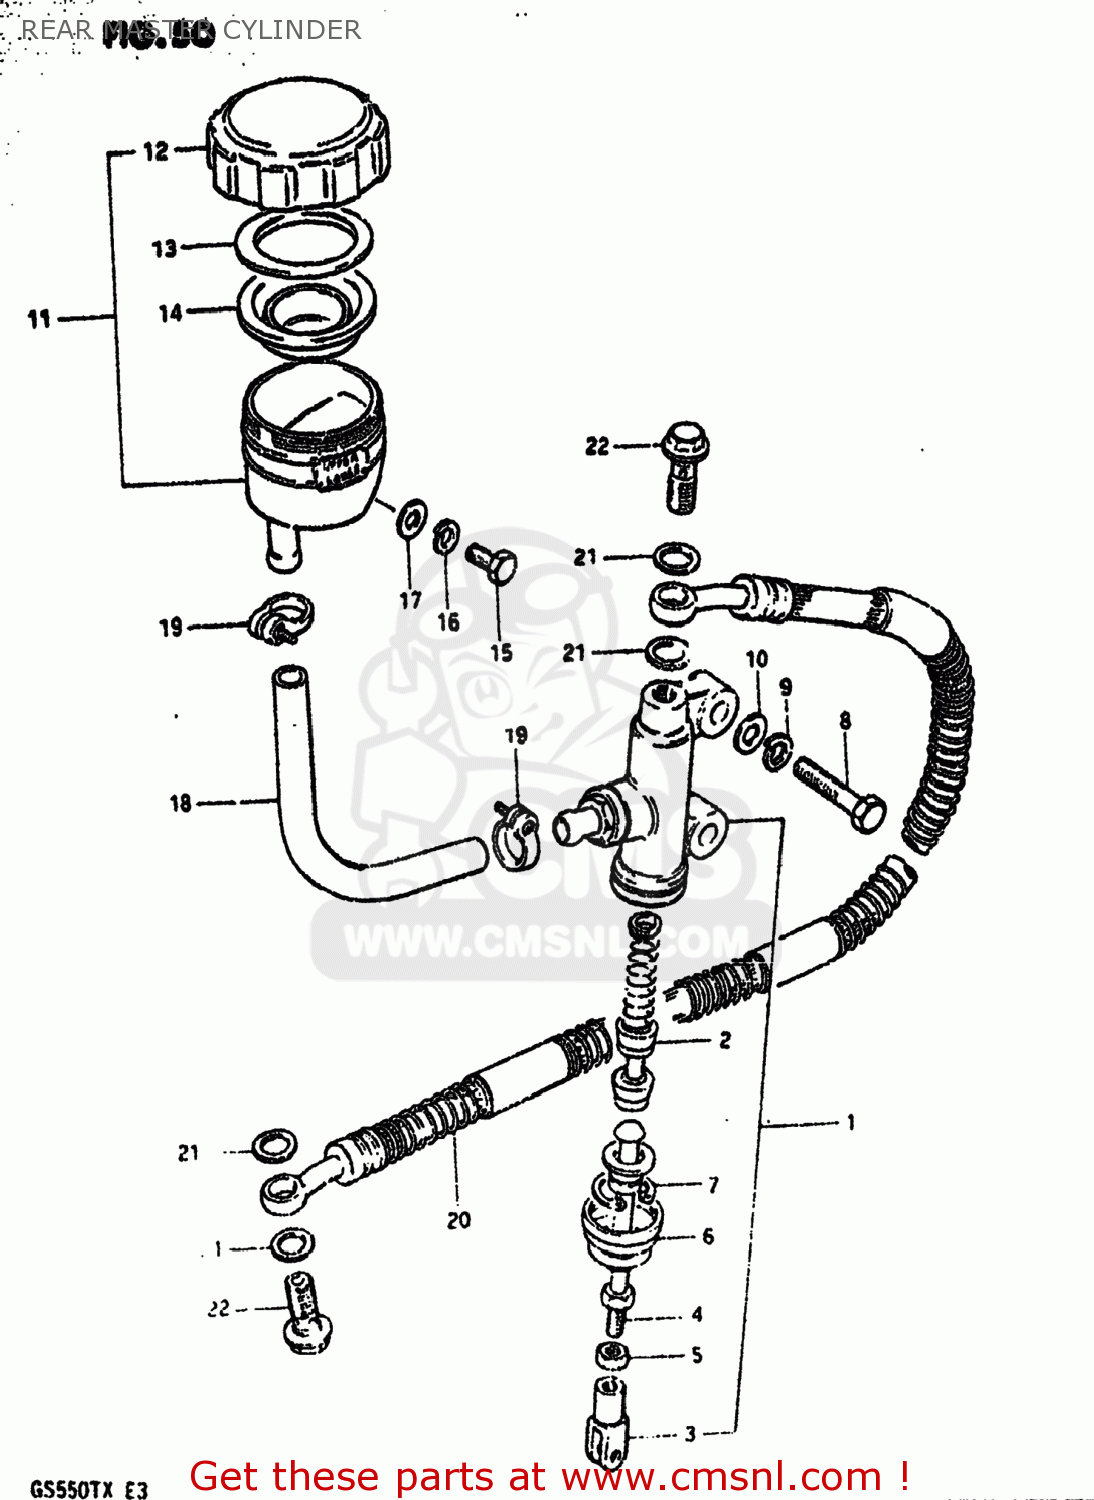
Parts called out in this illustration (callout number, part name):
1	CYLINDER ASSEMBLY,REAR MASTER
2	PISTON/CUP SET
3	YOKE
4	ROD,PUSH
5	NUT
6	BOOT
7	CIRCLIP
8	BOLT (8X30)
9	LOCK WASHER
10	WASHER
11	TANK ASSEMBLY,RESERVOIR
12	CAP
13	PLATE,DIAPHRAGM
14	DIAPHRAGM
15	BOLT, UPPER
16	LOCK WASHER
17	WASHER
18	HOSE,RESERVOIR TANK
19	CLAMP
20	HOSE,REAR BRAKE
21	WASHER
22	BOLT,UNION
